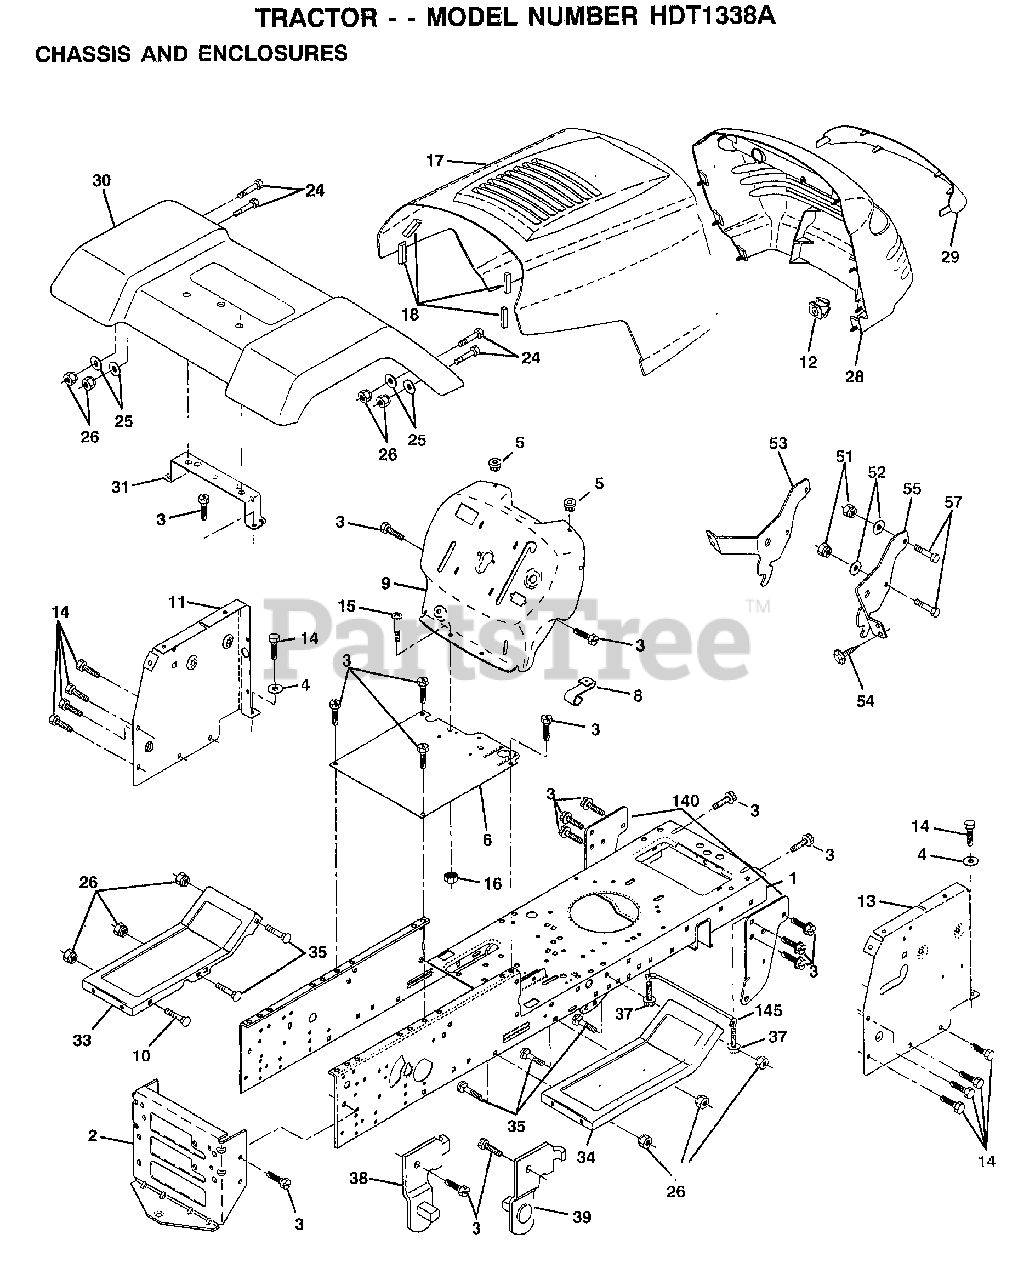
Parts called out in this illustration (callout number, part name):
1	CHASSIS.STAMPING
3	SCREW
4	WASHER
5	BUMPER-HOOD/DASH
6	SADDLE-SILKSCREEN
8	CLIP.RETAINER
9	DASH SILKSCREEN
11	"PANEL-DASH,LH"
12	CLIP.TINNERMAN
13	PANEL.ASM.SLKSCR.DASH.RH
14	SCREW LT
15	SCREW
17	HOOD.STEEL.ASSY
20	"PLATE-MTG,BATT/FU"
24	BOLT
25	WASHER
26	NUT
28	GRILLE-MS428
29	LENS.GRILLE.PRIVATE LABEL
30	FENDER.PNTL.LT.W/O.SHIFT
31	BRKT FENDER
33	FOOTREST.LH.PERF.
34	FOOTREST.RH.PERF.
35	BOLT
37	SCREW LT
38	BRACKET ASM LH
39	BRACKET ASM RH
51	NUT
52	WASHER
53	BRACKET.GRILLE.LH
54	SCREW.HEX.WS.HD
55	BRACKET.GRILLE.RH
140	BRKT SUSPENSION
145	"ROD POVOT,CHASSIS"
